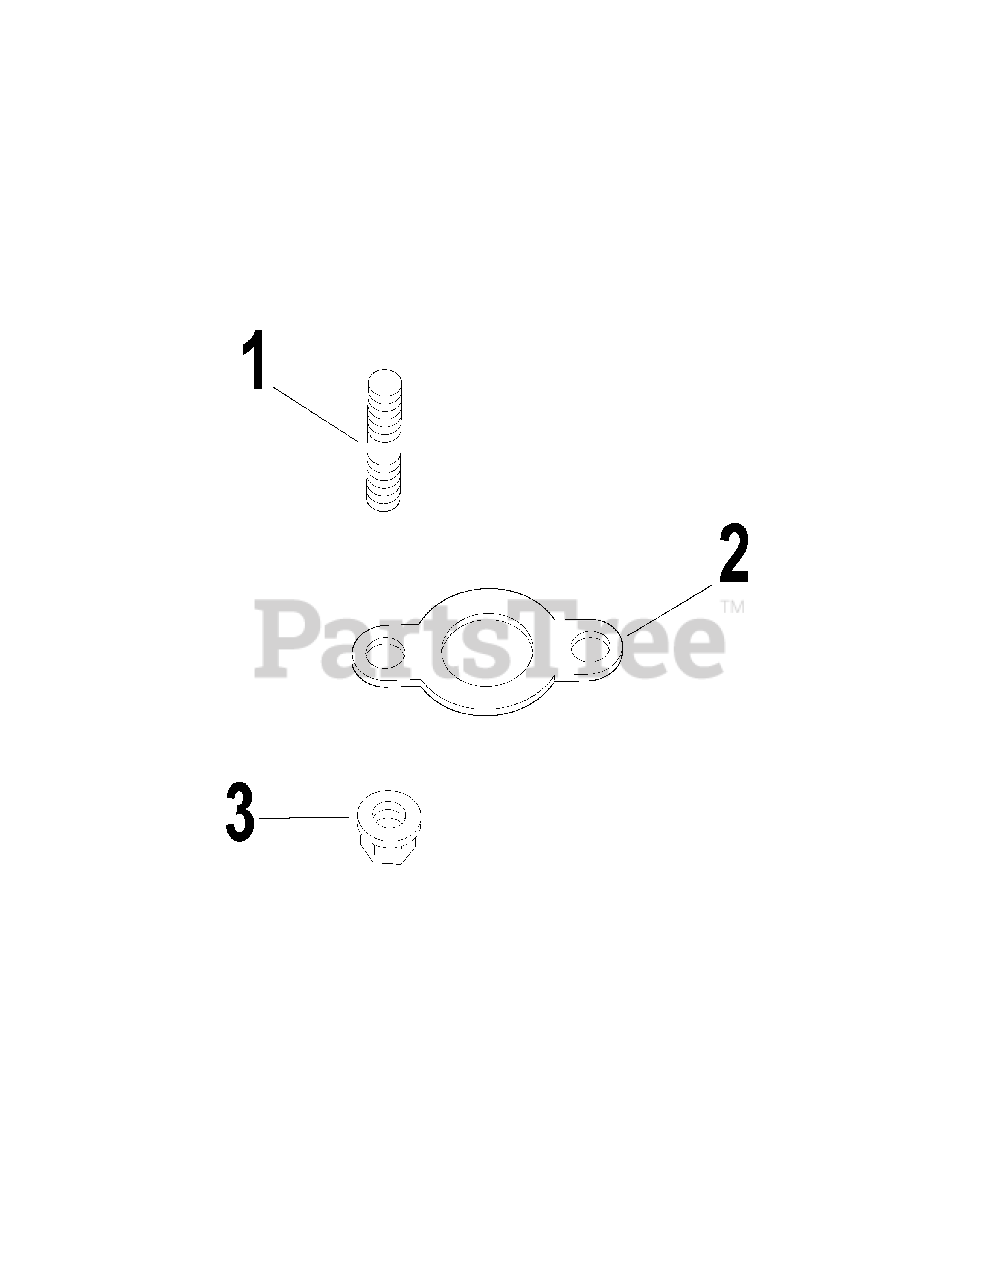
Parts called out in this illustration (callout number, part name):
1	Stud M8x1 25x33 (4)
2	Gasket, exhaust manifold (2)
3	Nut, hex flange M8x1 25 (5)
